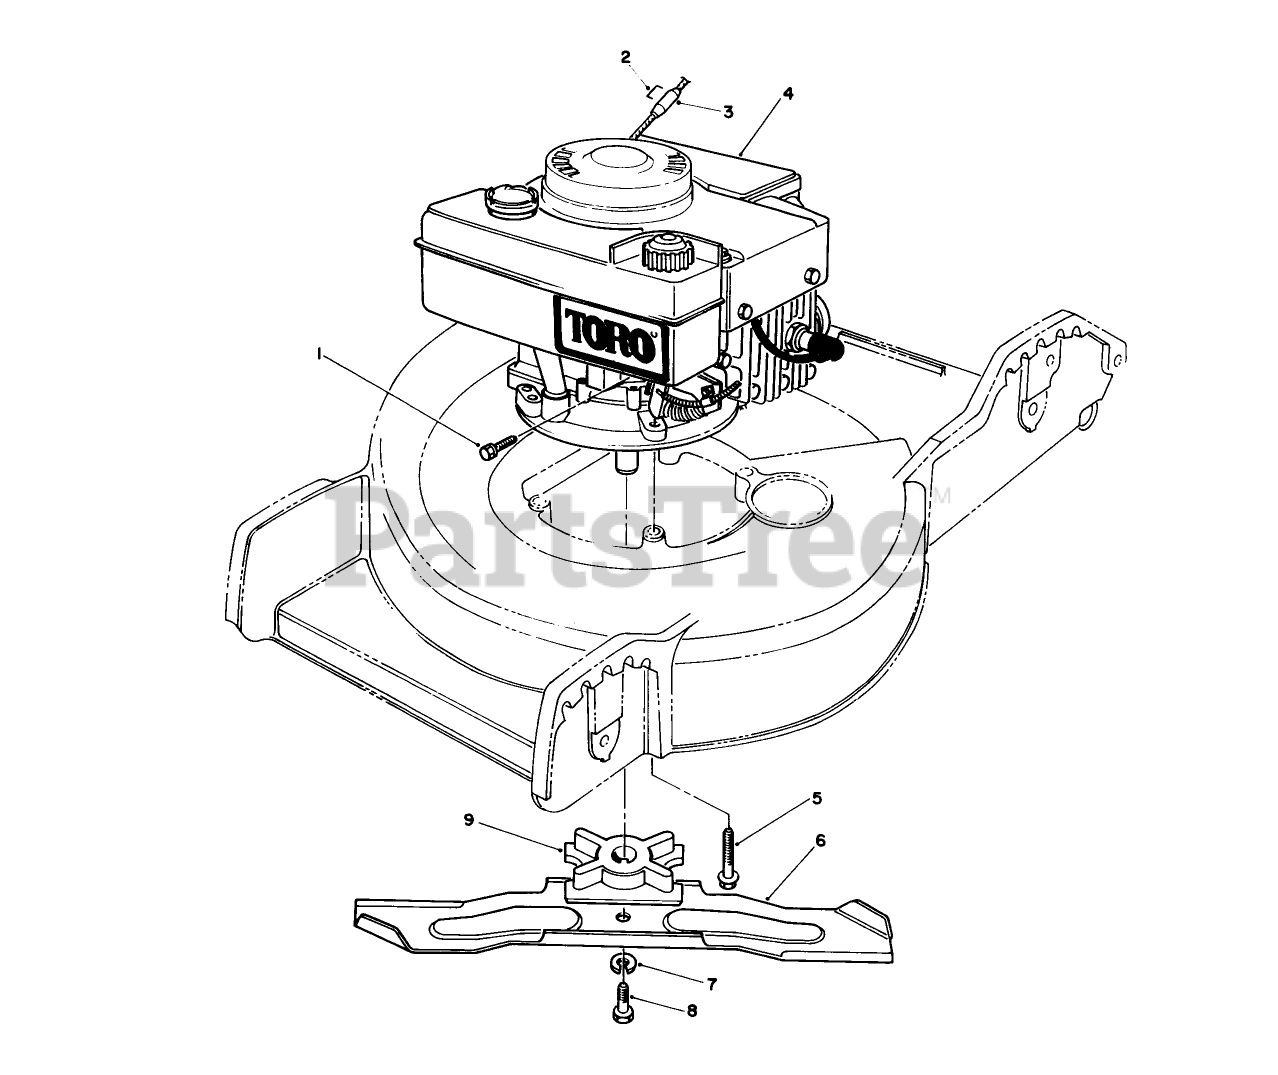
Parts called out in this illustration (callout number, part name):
1	SCREW-HH
2	Staple
3	Stop-Rope
5	3/8-16 X 2 CAPSCREW
6	Blade
7	WASHER-LOCK
8	SCREW-HH
9	BLADE RETAINER
